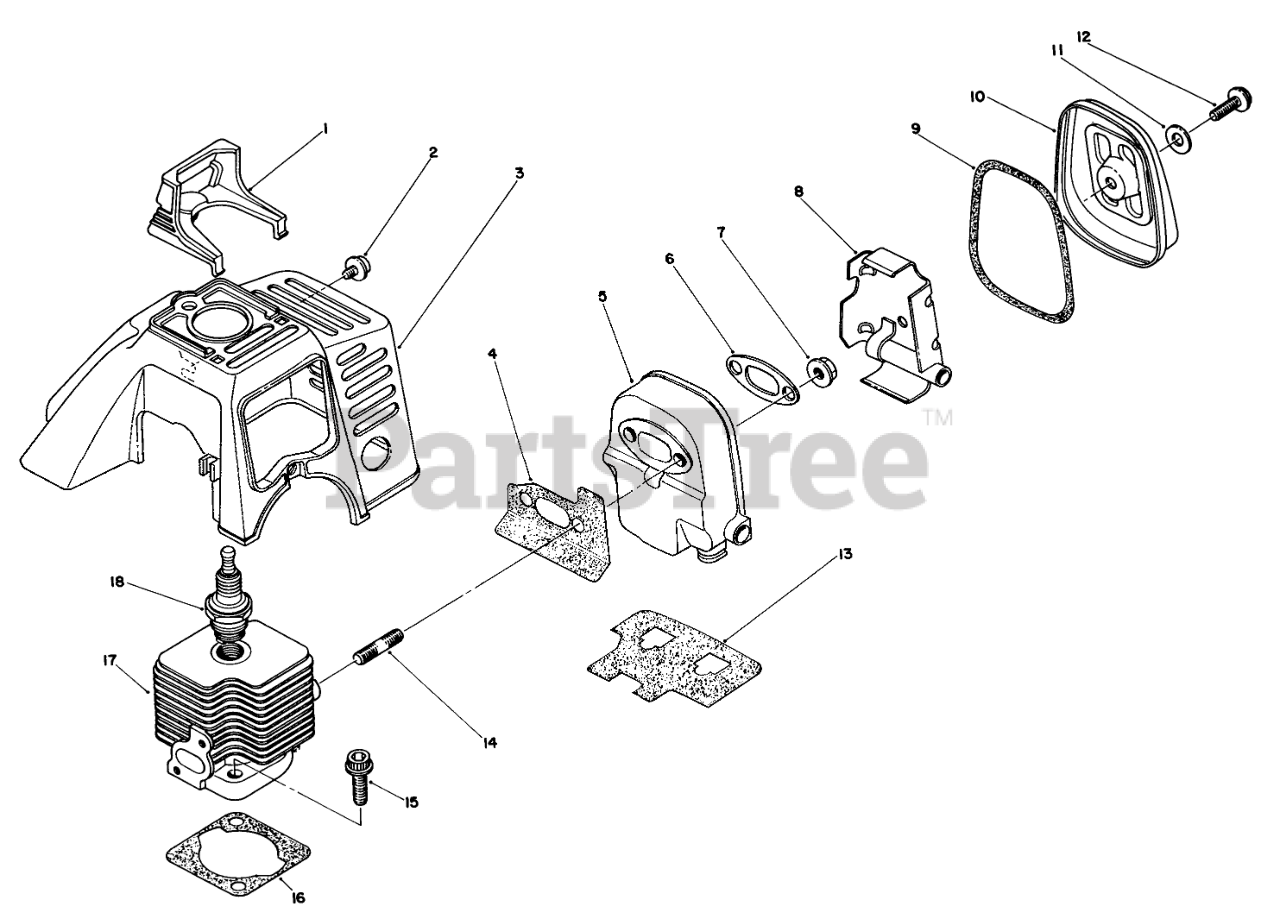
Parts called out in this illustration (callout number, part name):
1	SPARK PLUG GUARD
2	SCREW & WASHERE
3	COVER-TOP
4	Gasket-Muffler
5	Body-Muffler
6	PLATE
8	Plate
9	GASKET
10	MUFFLER LID
11	Washer-Seal
12	Bolt-Flange
13	Gasket
15	FLANGE BOLT
16	CYL GASKET
17	Cylinder
18	Spark Plug
